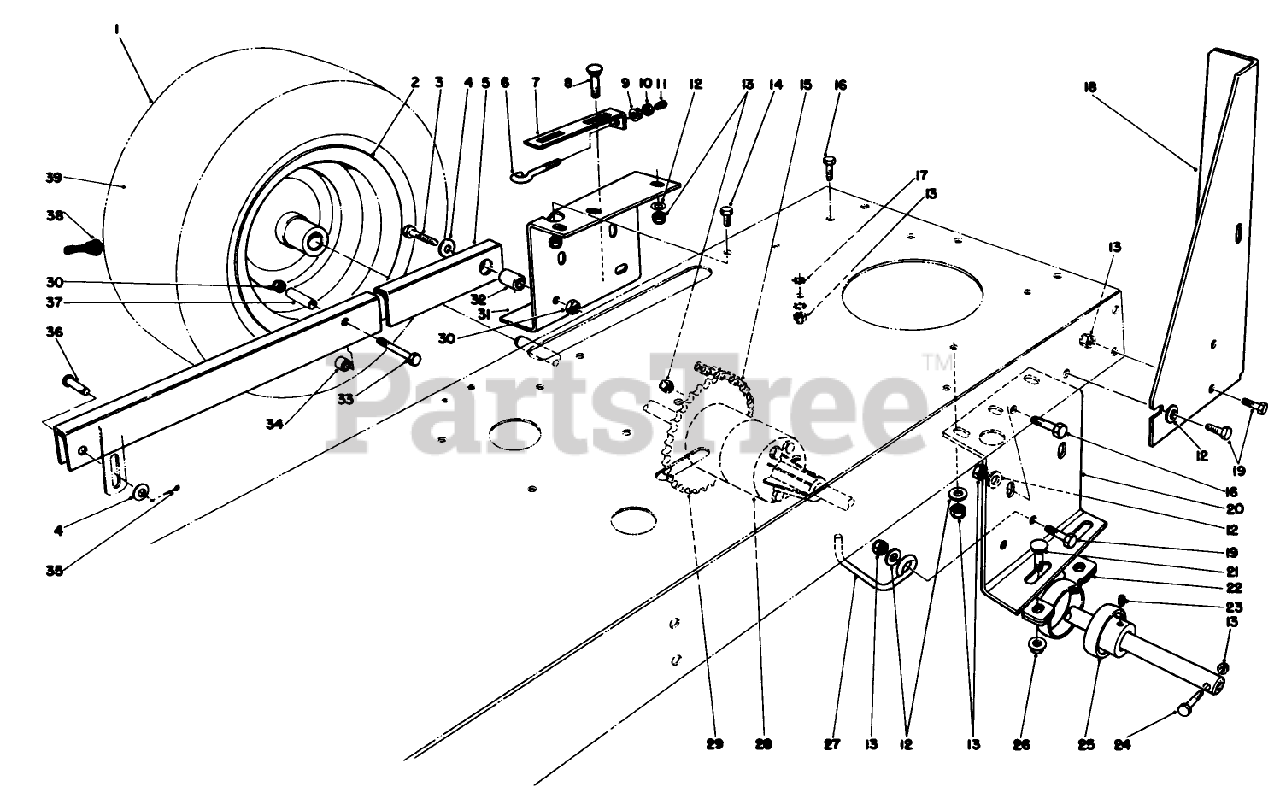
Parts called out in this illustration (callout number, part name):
3	SCREW-HH
4	WASHER-FLAT
6	SCREW-ADJUSTING
7	PLATE-ADJUSTING
8	BOLT-CARR
9	NUT-HF
10	NUT-HEX
11	VINYL ROD TIP
12	WASHER-PLAIN
13	NUT-LOCK, NI
14	SCREW-HH
15	ROLLER CHAIN
16	SCREW-HH
17	WASHER-LOCK, INTERNAL
18	LH STANDBAR *B
19	SCREW-HH
20	LH REAR AXLE SU
21	SCREW-CARR
22	RTNR-PILLOW BLK
23	SCREW-SET, HSH
24	SCREW-HH
25	BEARING-BALL
26	NUT-HF
27	BELT GUIDE
29	42T DIFF SPROCKET
30	NUT-LOCK, CONE
31	RH REAR AXLE SUPT *R
32	SPACER
33	SCREW-HH
34	INNER TUBE SPACER
35	PIN-COTTER
36	PIN-CLEVIS
39	TUBE-INNER
